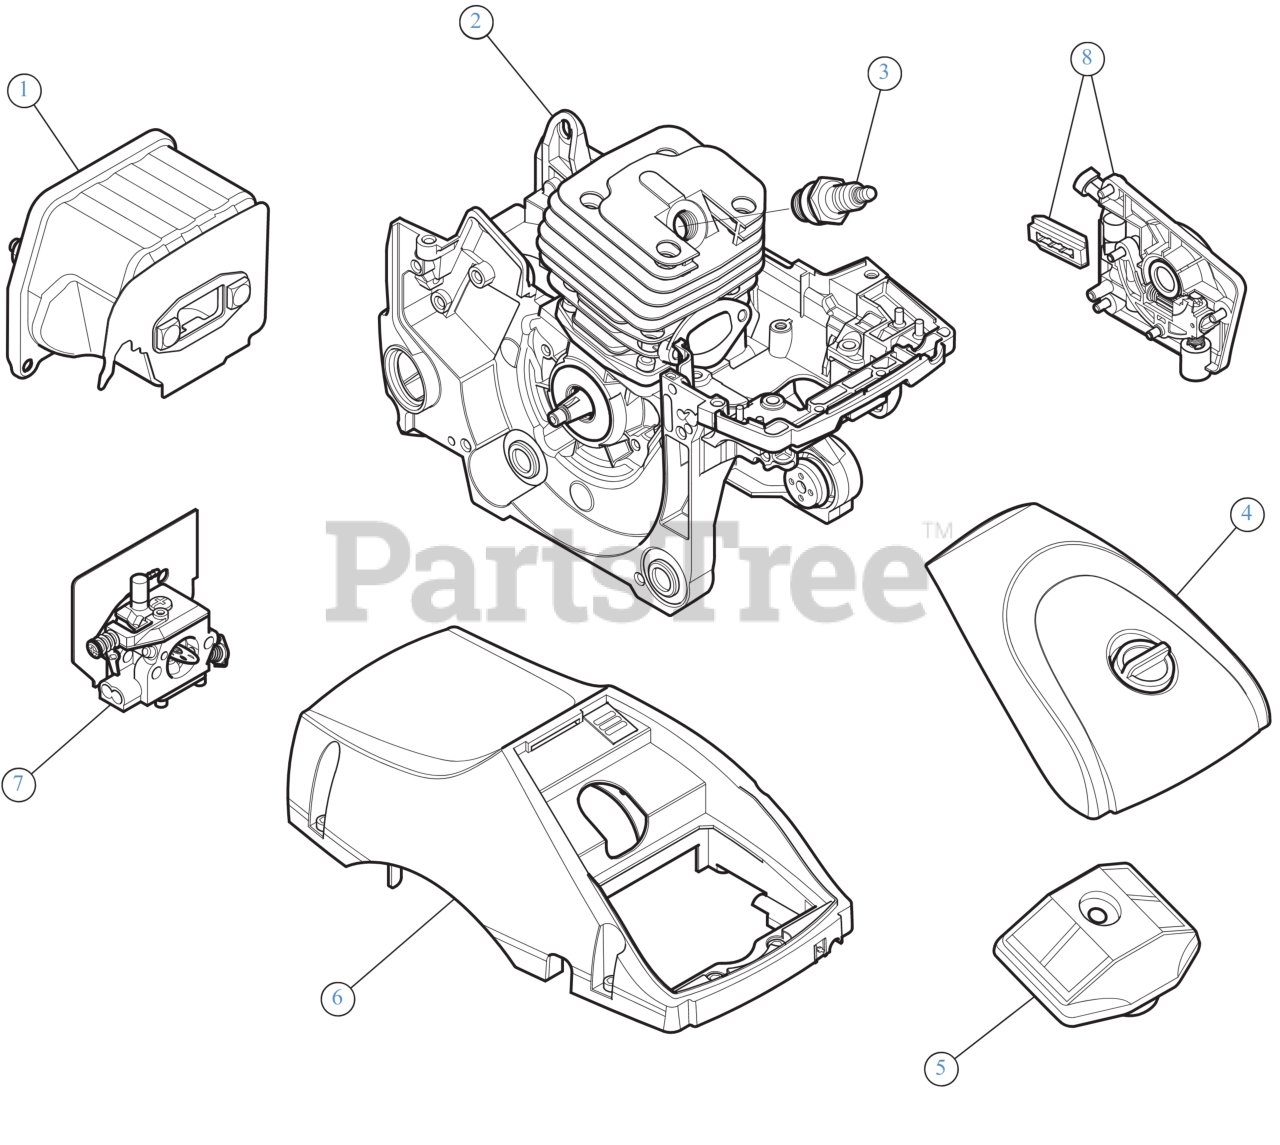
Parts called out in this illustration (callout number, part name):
1	MUFFLER ASSEMBLY
2	SHORTBLOCK 46CC
3	SPARK PLUG:L8RTF YD4500-26200
4	AIR FILTER COVER ASSEMBLY
5	AIR FILTER W/SEAL
6	COVER
7	CARBURATOR
8	PUMP ASM:OIL
